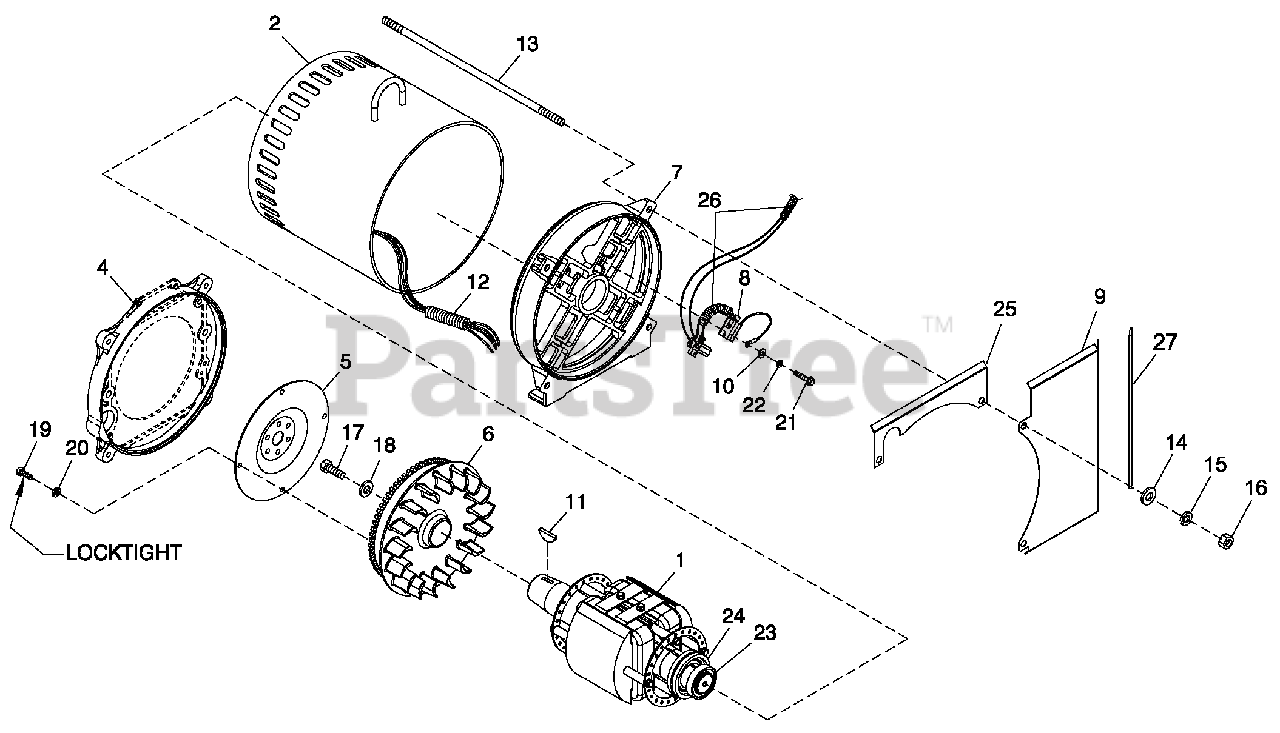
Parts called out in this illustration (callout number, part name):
1	ROTOR-2390-45KD1 CPL
2	STATOR-390 45K 2P 1PH DIRECT
3	INSTR HYP0T TEST (NOT SH0WN)
4	ENGINE ADAPTER
5	FLEXPLATE
6	ASSY FLYWHEEL CPL W/40MM FAN B
7	REAR BEARING CARRIER 390/DRCT
8	ASSY BRUSH H0LDER 390/HSB
9	GUARD REAR BEARING CARRIER
10	WASHER FLAT #8 ZINC
11	KEY W00DRUFF #E
12	CONDUIT FLEX 1.0" ID (35" LG)
13	STUD M 14-2.0 570 G5 ZINC
14	WASHER FLAT M14
15	WASHER L0CK M14
16	NUT HEX M14-2.0 G8 YEL CHR
17	SCREW HHC M16-2.0 X 45 G8.8
18	SPACER .69 X 2.75 X .37 ST/ZNC
19	SCREW HHC M10-1.50 X 16 G10.9
20	WASHER LOCK M10
21	SCREW HHTT M4-0.7 X 16 BP
22	WASHER L0CK #8-M4
23	BALL BEARING-45 MM
24	SLIP RING MACHINED
25	GUARD REAR BEARING CARRIER
26	CONDUIT FLEX .38" ID (60")
27	TRIM VINYL BLACK 1/8GP (16.5"LG)
